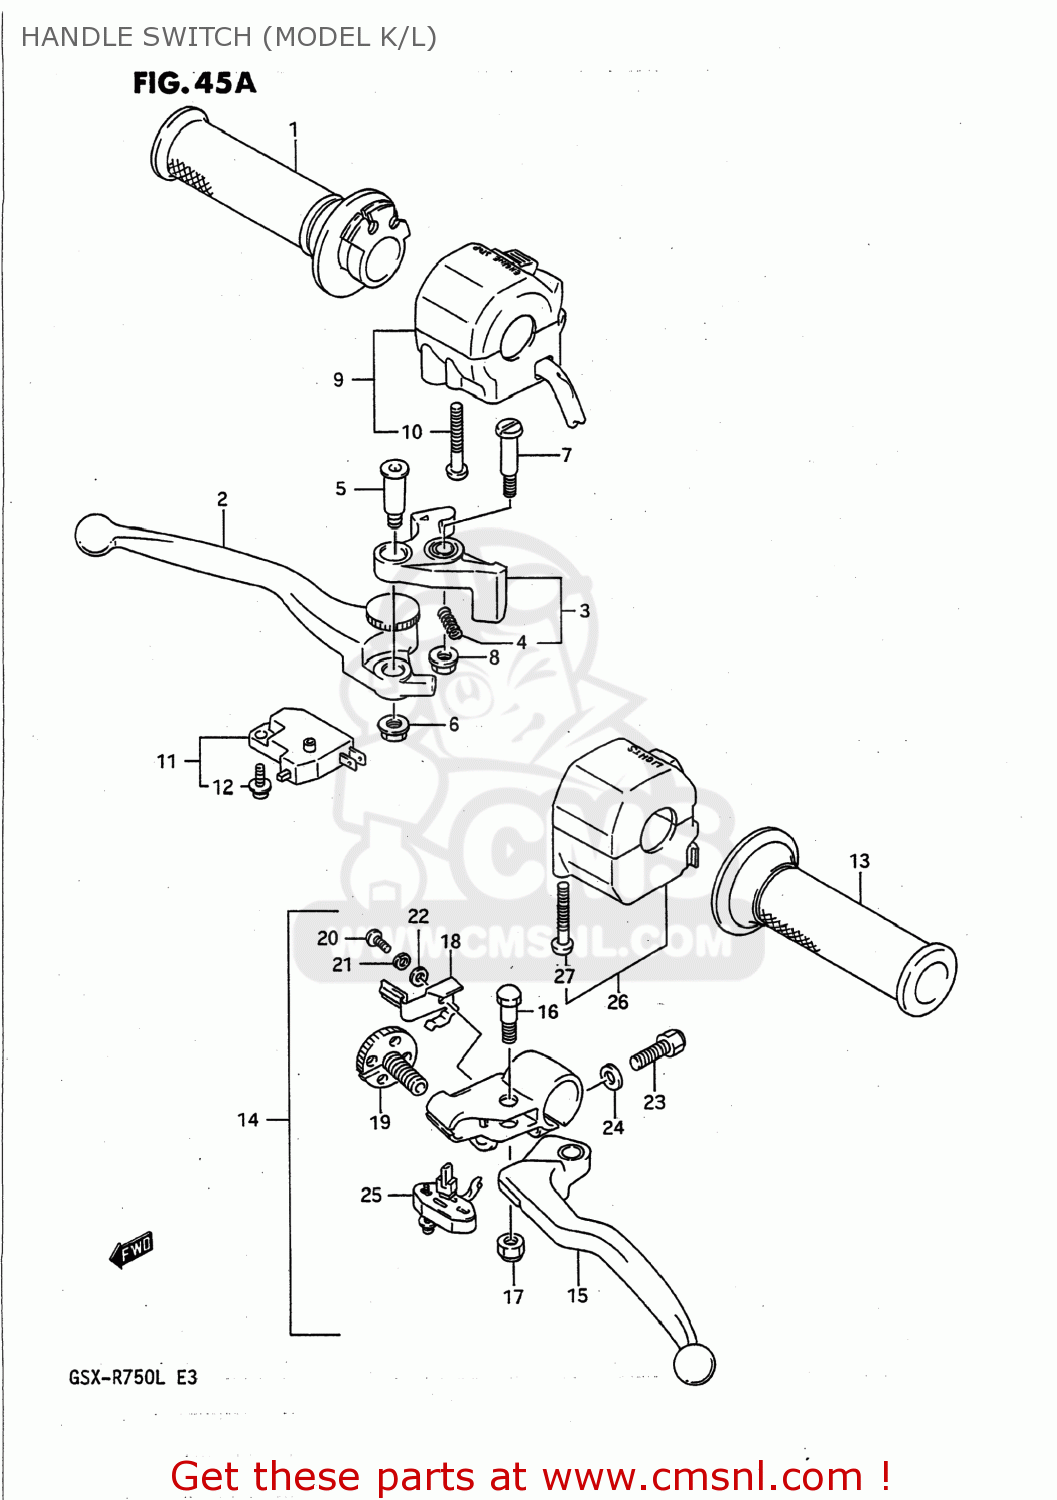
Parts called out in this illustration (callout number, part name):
1	GRIP,THROTTLE
2	LEVER,ADJUST
3	KNOCKER
4	SPRING
5	BOLT,LEVER
6	NUT
7	BOLT,LEVER PIVOT
8	NUT 6MM
9	SWITCH ASSEMBLY,HANDLE,RIGHT
10	SCREW, 5X45
11	SWITCH ASSEMBLY,STOP
12	SCREW
13	GRIP,L
14	LEVER ASSEMBLY
15	LEVER,CLUTCH
16	BOLT,LEVER PIVOT
17	NUT
18	ADJUST,SPRING
19	ADJUSTER,LOCK
20	SCREW 4X6
21	WASHER,LOCK 4M
22	WASHER 4MM
23	BOLT
24	WASHER
25	SWITCH ASSEMBLY,CLUTCH
26	SWITCH ASSEMBLY,HANDLE,LEFT
27	SCREW, 5X45
